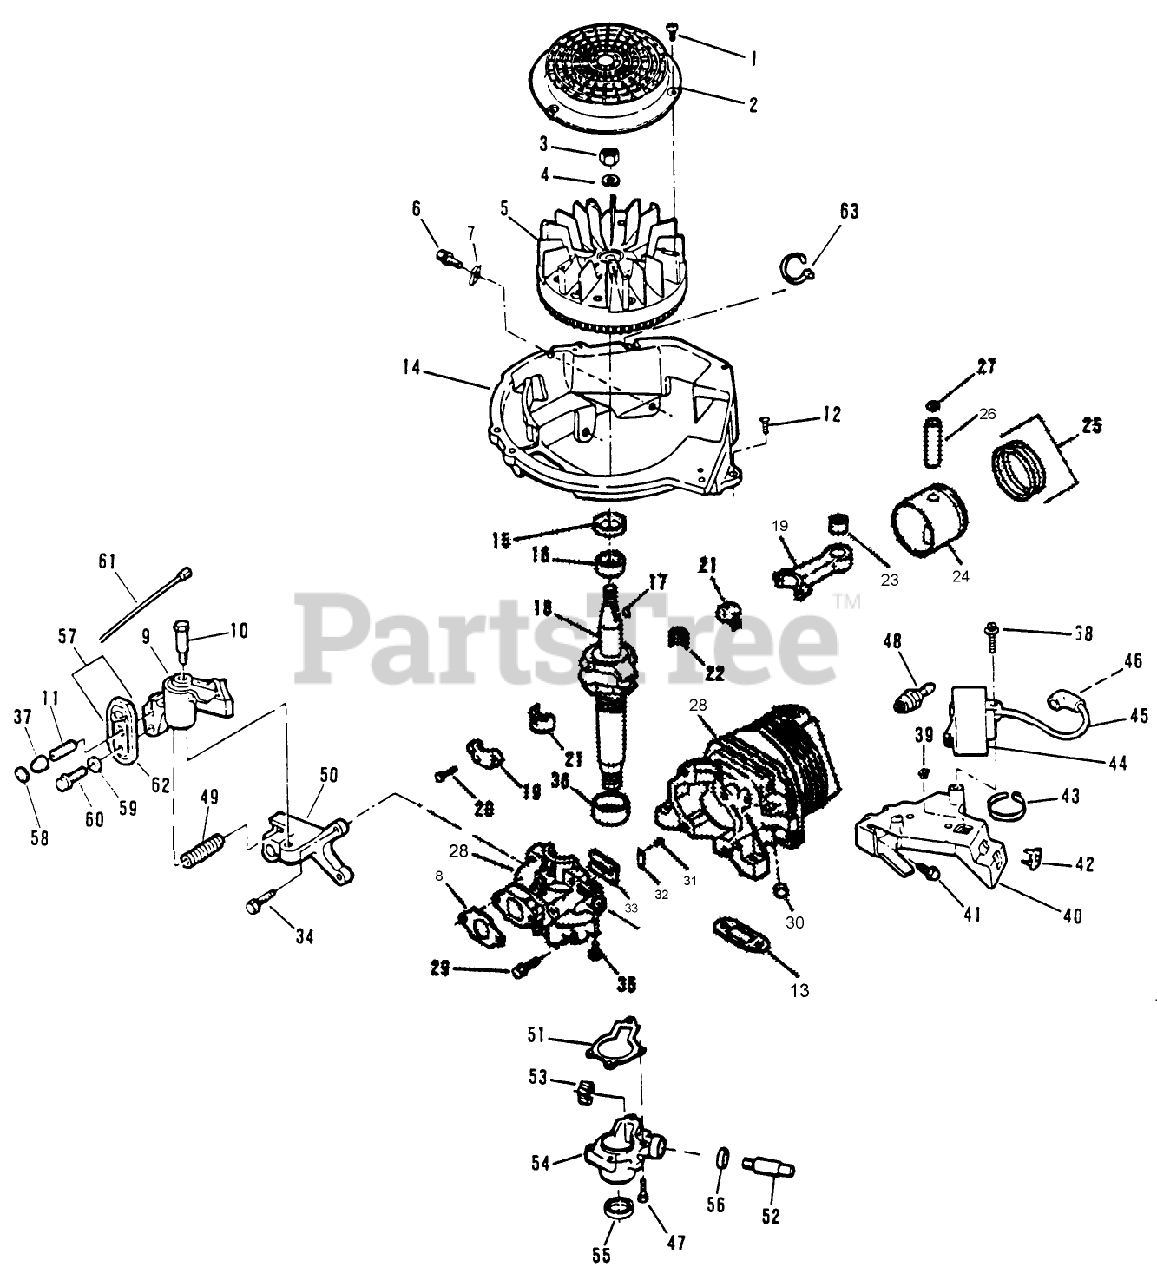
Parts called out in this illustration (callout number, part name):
1	SCREW F
3	NUT
5	FLYWHEEL ASSY F
6	SCREW-SEMS
8	GASKET CARB S
10	SCREW-SHOULDER
11	SPRING
12	SCREW F
13	GASKET-EXHAUST F
15	SEAL-OIL
16	BEARING V
17	KEY
20	SCREW-HSH
21	LINER ASM
22	BEARING-NEEDLE
23	BEARING AY F
27	RING-RETAINING
29	SCREW-H.W.HD. F
30	PLUG-CORE VF
31	SCREW-HH
32	PLATE-BACKUP, REED
34	SCREW
36	BEARING S
37	ACTUATOR-LEVER, BRAKE
39	NUT-CLIP
40	C.D. BRKT F
42	NUT-CLIP
45	HT LEAD&COVER XEV
49	SPRING-BRAKE
50	BRACKET-BRAKE F
51	GASKET S
52	DR SHAFT,PTO S
55	SEAL-OIL
56	SEAL S
58	RETAINER S
59	WASHER
61	WIRE LEAD AY F
